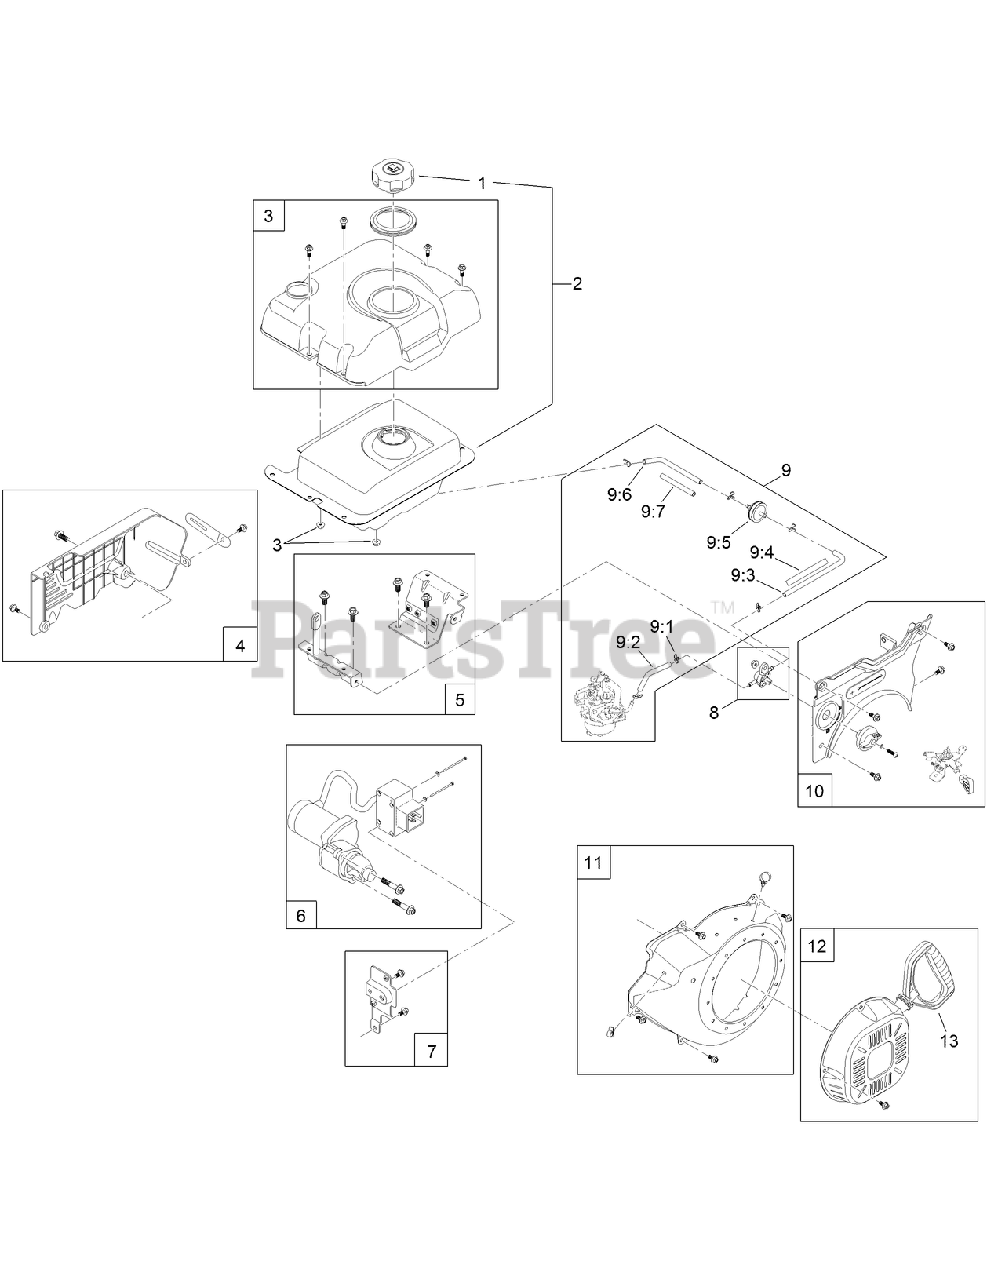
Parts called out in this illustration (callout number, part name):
3	FUEL TANK COVER KIT
4	REAR PANEL AND HARDWARE KIT
5	TANK MOUNT BRACKET KIT
7	SWITCH BOX BRACKET KIT
8	FUEL SHUT-OFF VALVE KIT
9:1	Clamp-Hose
9:2	Hose-Fuel
9:3	Hose-Fuel
9:4	SLEEVE-ABRASION
9:5	Filter-Fuel
9:6	Hose-Fuel
9:7	SLEEVE-ABRASION
10	FRONT PANEL KIT
11	RECOIL SHROUD KIT
12	RECOIL KIT
13	HANDLE-RECOIL
